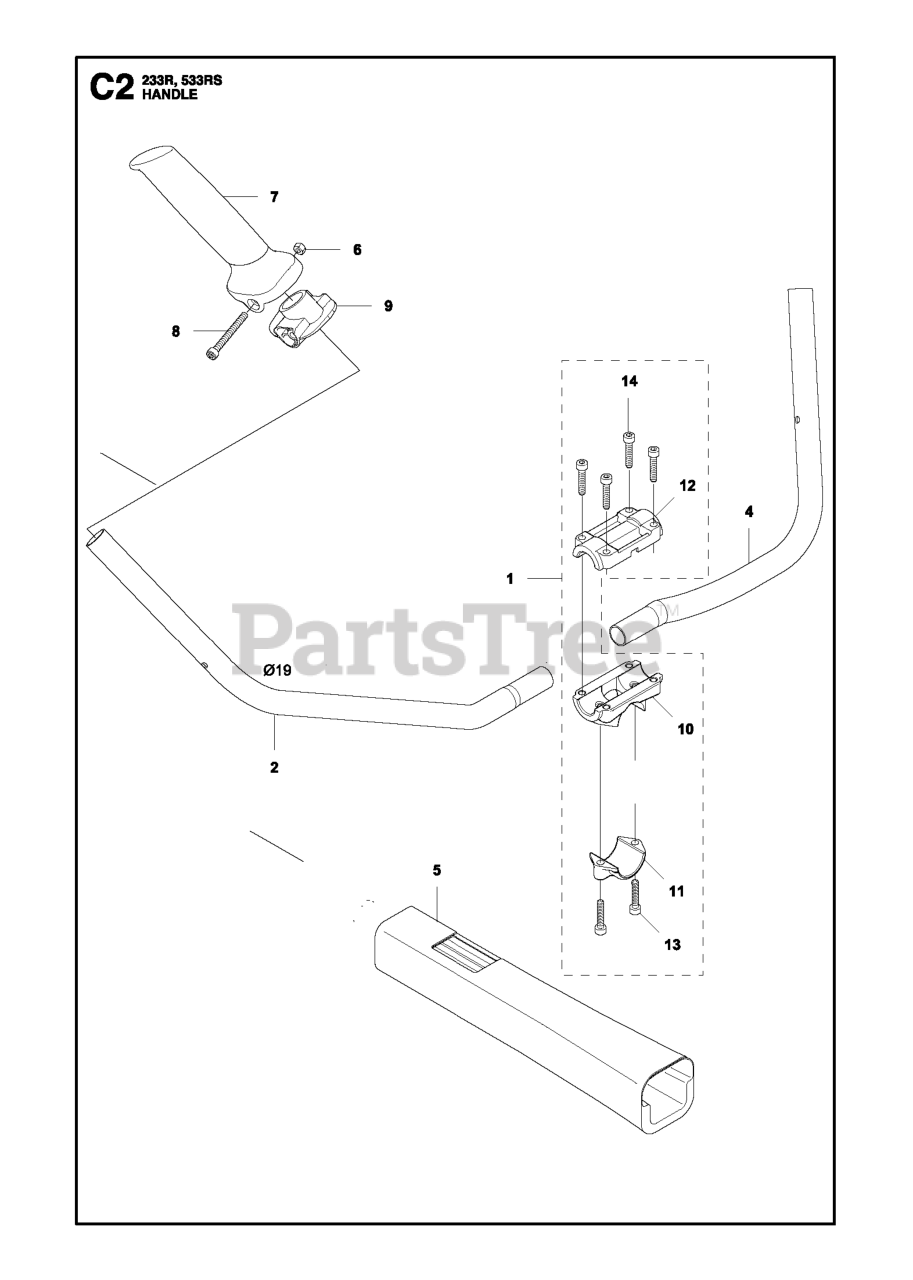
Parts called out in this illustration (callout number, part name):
1	BRACKET ASSY.
5	PROTECTOR (RPLS 405017110)
6	NUT
13	BOLT
